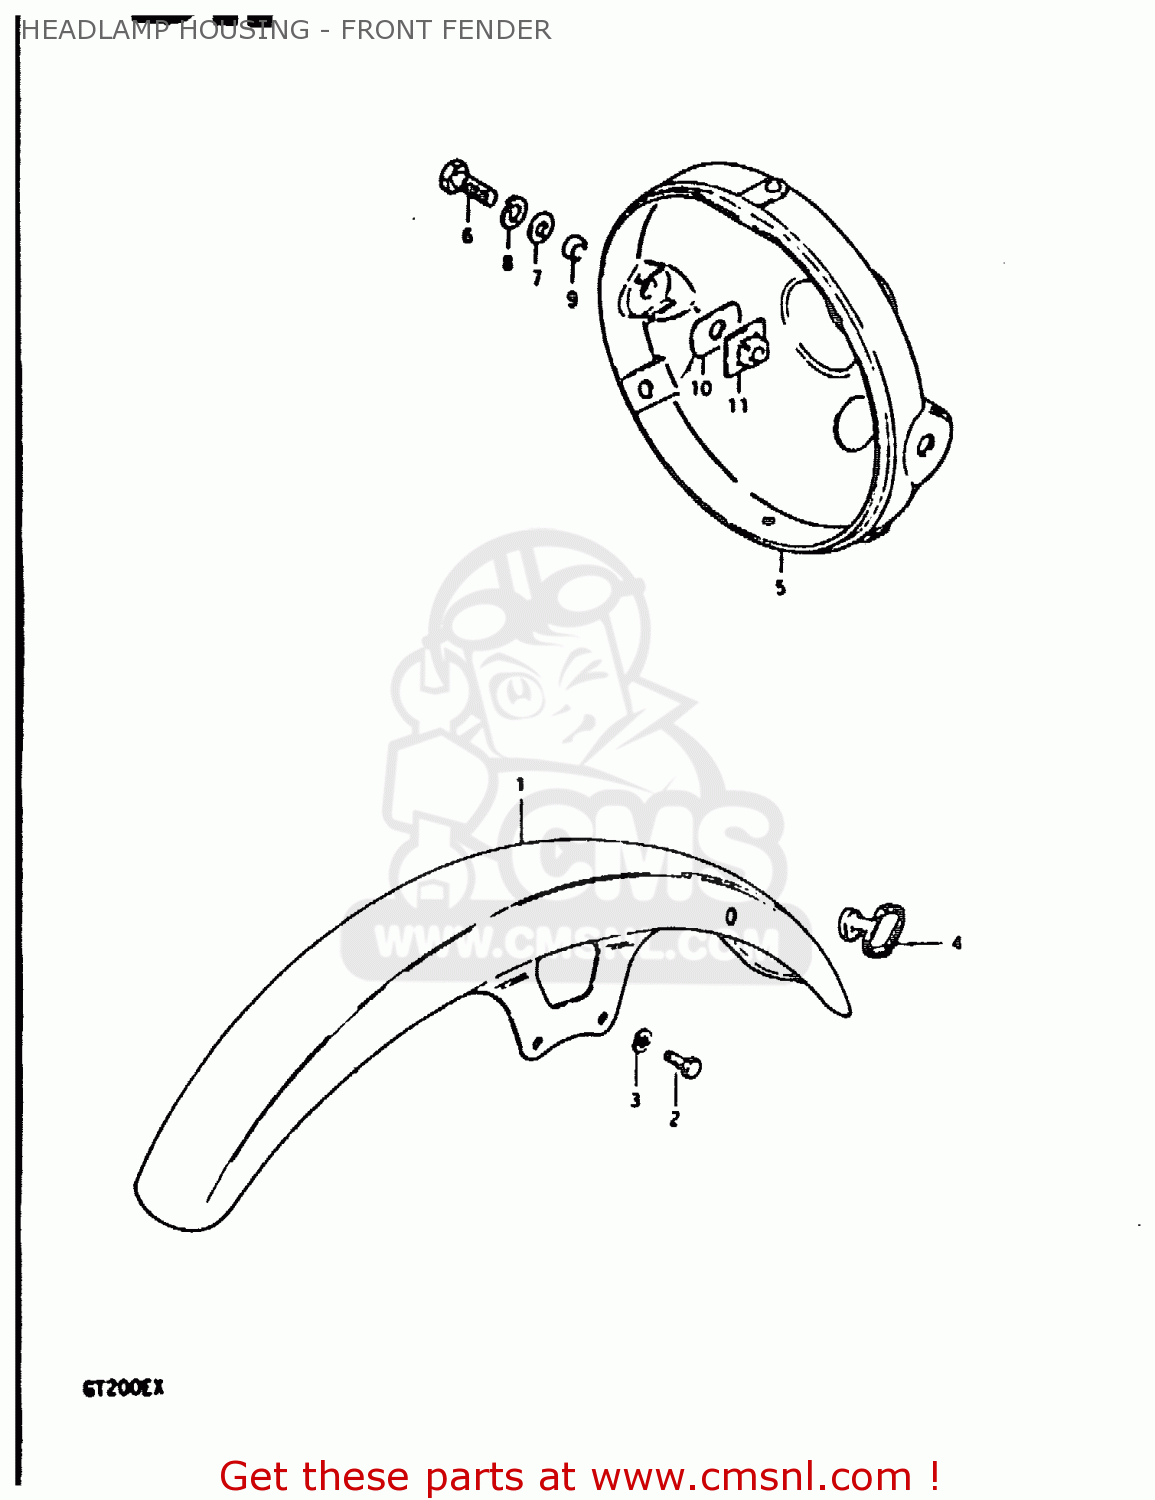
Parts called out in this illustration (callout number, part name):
1	FENDER,FR
2	BOLT
3	LOCK WASHER
4	GUIDE,CABLE
5	HOUSING,HEADLAMP(BLACK)
6	BOLT
7	WASHER
8	LOCK WASHER
9	SPACER (8.8X12X7)
10	CUSHION
11	PLATE,HEADLAMP HOUSING
